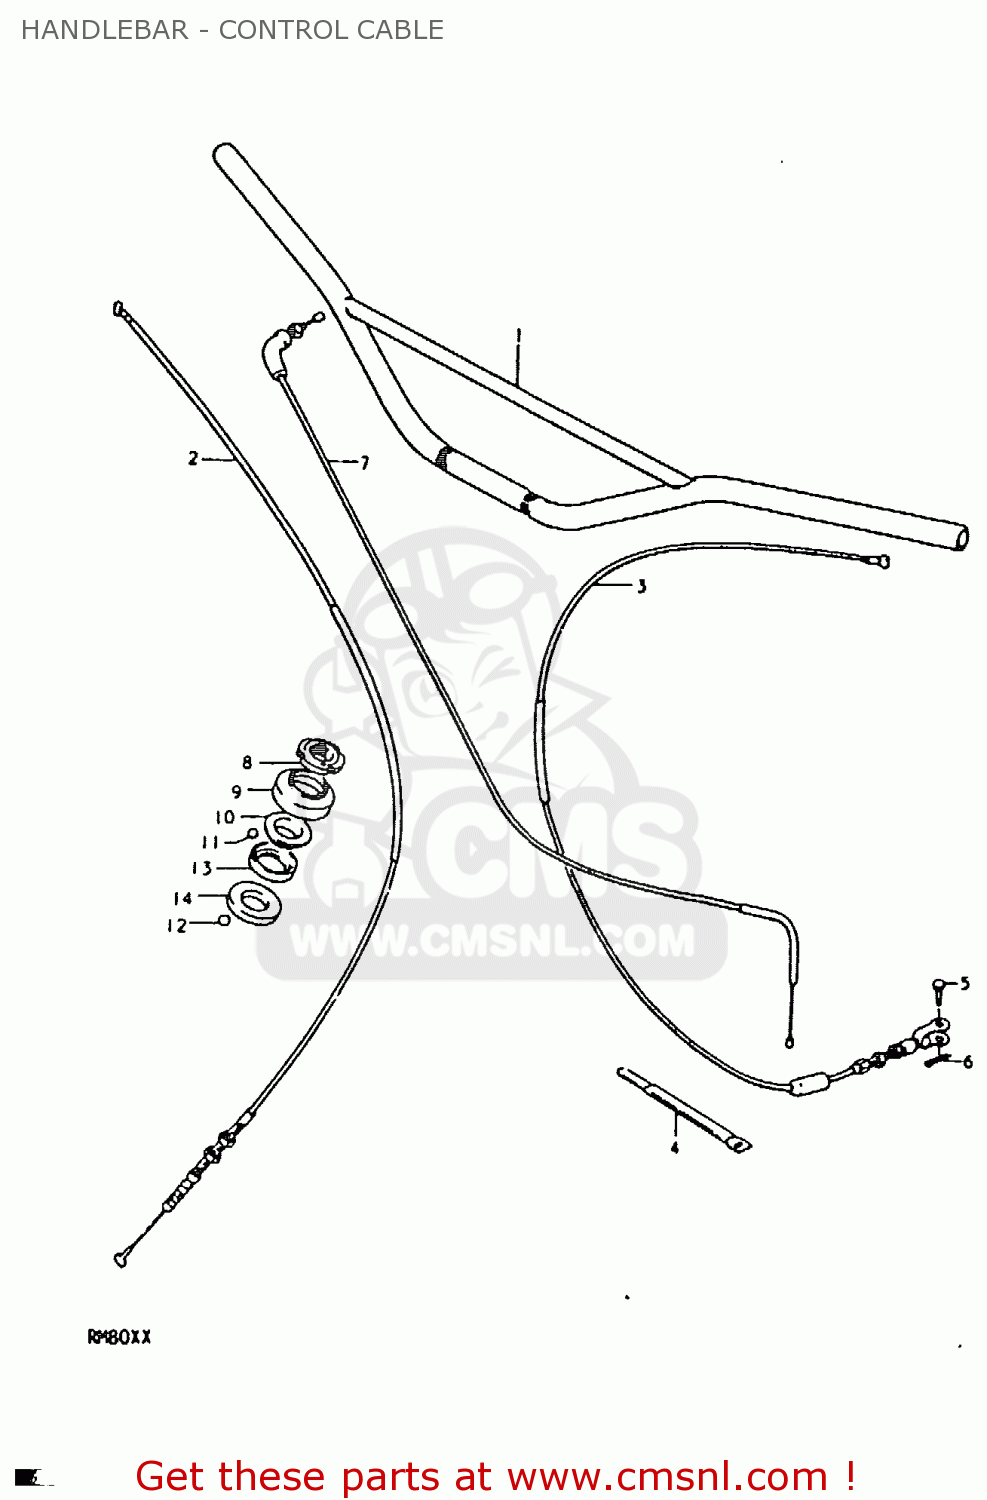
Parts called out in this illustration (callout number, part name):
1	HANDLEBAR
2	CABLE,FR BRAKE
3	CABLE ASSEMBLY,CLUTCH
4	CLAMP
5	PIN(L:13)
6	PIN
7	CABLE ASSEMBLY,THROTTLE
8	NUT,STEERING STEM(25X44X10)
9	DUST SEAL,STEERING UPR
10	RACE,STEERING OUTER UPR
11	BALL
12	BALL
13	RACE,STEERING INNER UPR
14	LACE,STEERING INNER LWR
